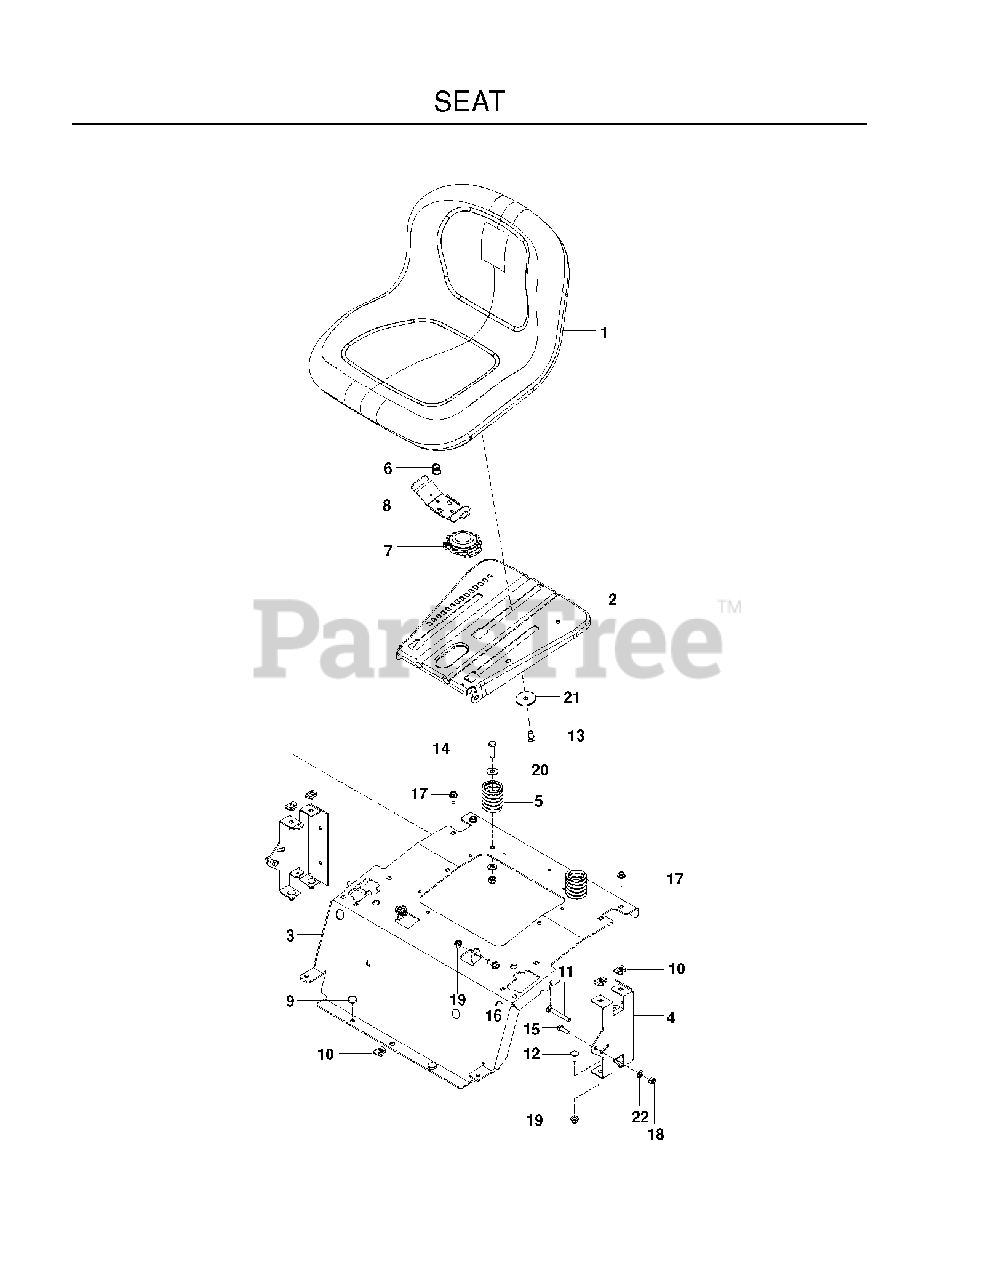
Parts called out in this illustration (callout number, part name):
1	SEAT.TG150.BLK.NLOGO.
2	PAN.ASM.SEAT.3PT
4	Rear Seat Support, Black
5	SPRING, SEAT
6	SPRING.LATCH.SEAT.TEX
7	SWITCH, SEAT N/C
8	HANDLE.SLIDE.SEAT.TEX.BLACK
9	GROMMET, BUMPER
10	U-CLIP 5/16-18 NUT RETAINER
11	RHSNB 5/16-18 X 2-1/2 GR5 ZD
12	BOLT 5/16C X 3/4" CARRIAGE
13	HCS 3/8-16 X 5/8 GR 5 ZD
14	HCS 3/8C X 1 1/4 GR5
15	HCS 5/16C X 1
16	BOLT, SHOULDER
17	BOLT 5/16-18 X 3/4
18	NUT 5/16 NYLOC
19	5/16-18 NYLOC FLANGE NUT
20	WASHER 3/8 FLAT
21	WASHER, 3/8 SPEC
22	FLAT WASHER 5/16 SAE
